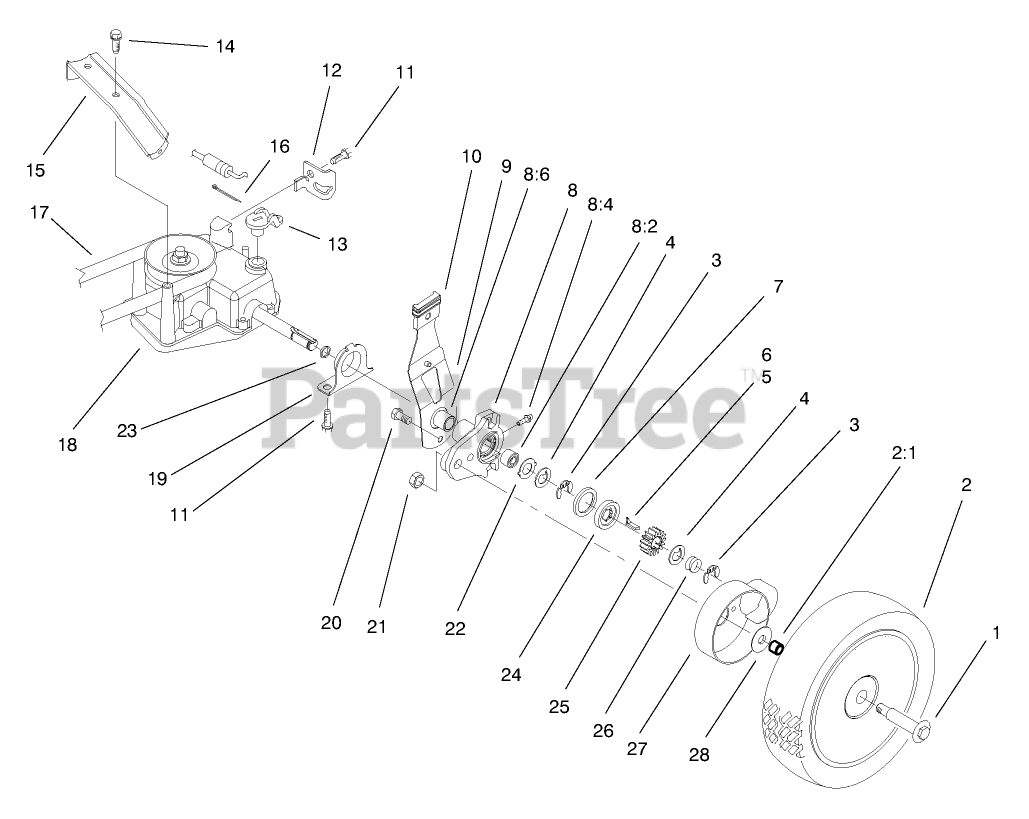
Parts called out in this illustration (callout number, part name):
1	WHEEL BOLT
2	WHL & TIRE ASSEMBLY
2:1	BUSHING
3	RING-RETAINING,CLIP
4	WASHER-THRUST, KEYED
5	KEY-ROCKING, LH
6	KEY-ROCKING, RH
7	RING-FRICTION
8	PIVOT ARM ASM
8:4	FITTING-GREASE
8:6	BUSHING
9	SPRING ARM ASM
10	KNOB-ARM
11	SCREW-HWHTF
12	RETAINER-CABLE
13	LEVER-SHIFT
14	SCREW-HWHTF
16	PIN-COTTER
17	V-BELT
18	GEARCASE ASM
19	CAP-END
20	SCREW-HSH, THREAD FORMING
21	NUT-LOCK
22	WASHER-ARM, PIVOT
23	O-RING
24	WASHER-CLUTCH
25	GEAR-PINION
26	SPRING-COMPRESSION
27	COVER-WHEEL
28	SPACER-COVER, WHEEL
